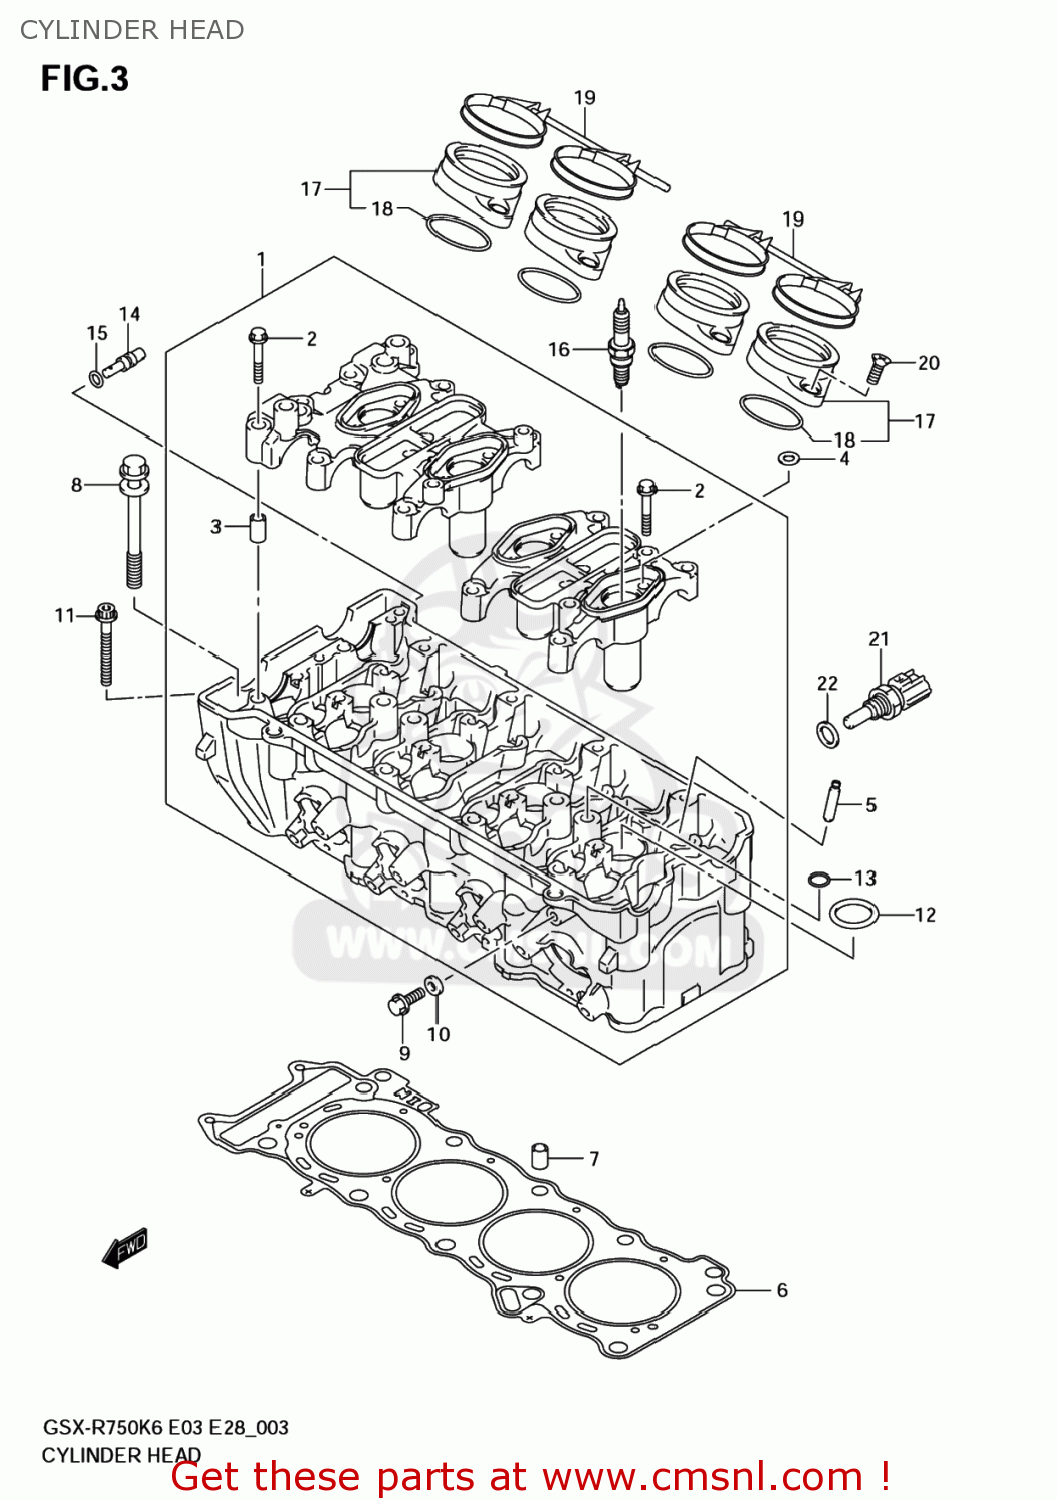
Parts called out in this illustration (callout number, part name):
1	HEAD ASSY,CYLINDER
2	BOLT(6X40)
3	PIN(6.2X8X16)
4	GASKET(6.2X13X1.2) (NAS)
5	GUIDE,VALVE(OS:0.3)
6	GASKET,CYLINDER HEAD (NAS)
7	PIN
8	BOLT,CYLINDER HEAD
9	BOLT(6X12)
10	GASKET(5.8X13X1.2) (NAS)
11	BOLT
12	O-RING
13	O RING(D:2.4,ID:10.8)
14	JET(8)
15	O RING(D:1.2,ID:4)
16	PLUG,SPARK(CR8E)
17	PIPE ASSY,INTAKE
18	O RING(D:2.4,ID:41.7)
19	CLAMP COMP,INT
20	SCREW (86X15.4
21	SENSOR,WATER TEMP
22	GASKET(12X17X1) (NAS)
